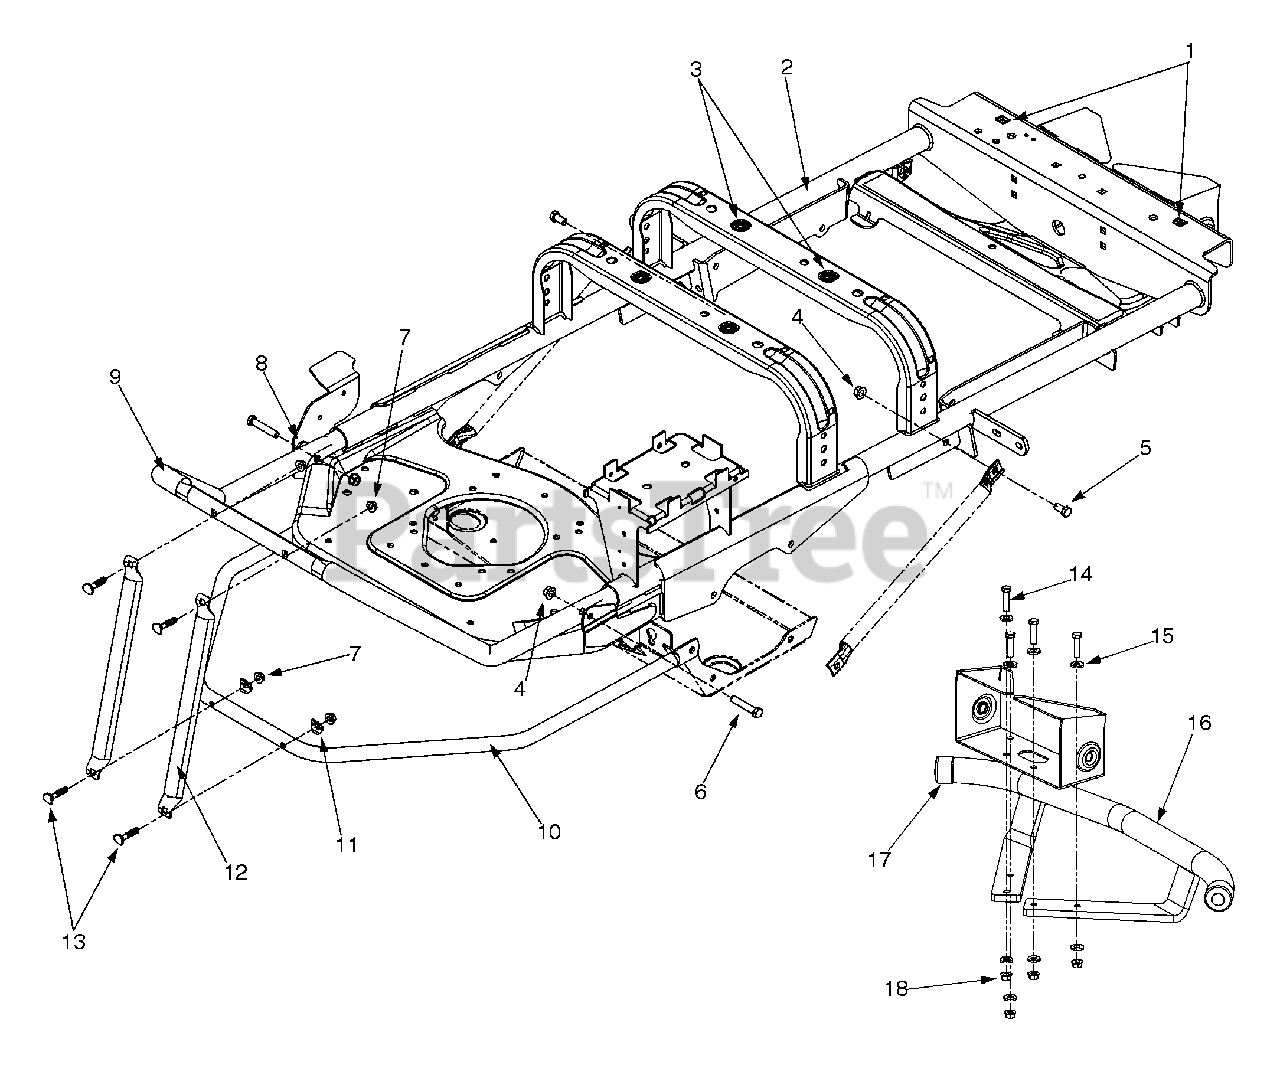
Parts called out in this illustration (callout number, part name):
1	Retainer Nut 3/8-16
2	Frame Assembly
3	Retainer Nut 3/8-16
4	Flange Lock Nut 3/8-16
5	Hex Cap Screw 3/8-16 x .75
6	Hex Cap Screw 3/8-16 x 2.0
7	Flange Lock Nut 5/16-18
8	Flat Washer .385 x 1.0 x .135
14	Hex Cap Screw 3/8-16 x 1.5
15	Flat Washer .406 ID x .875 OD
16	Front Bumper
17	End Cap
18	Flange Lock Nut 3/8-16
